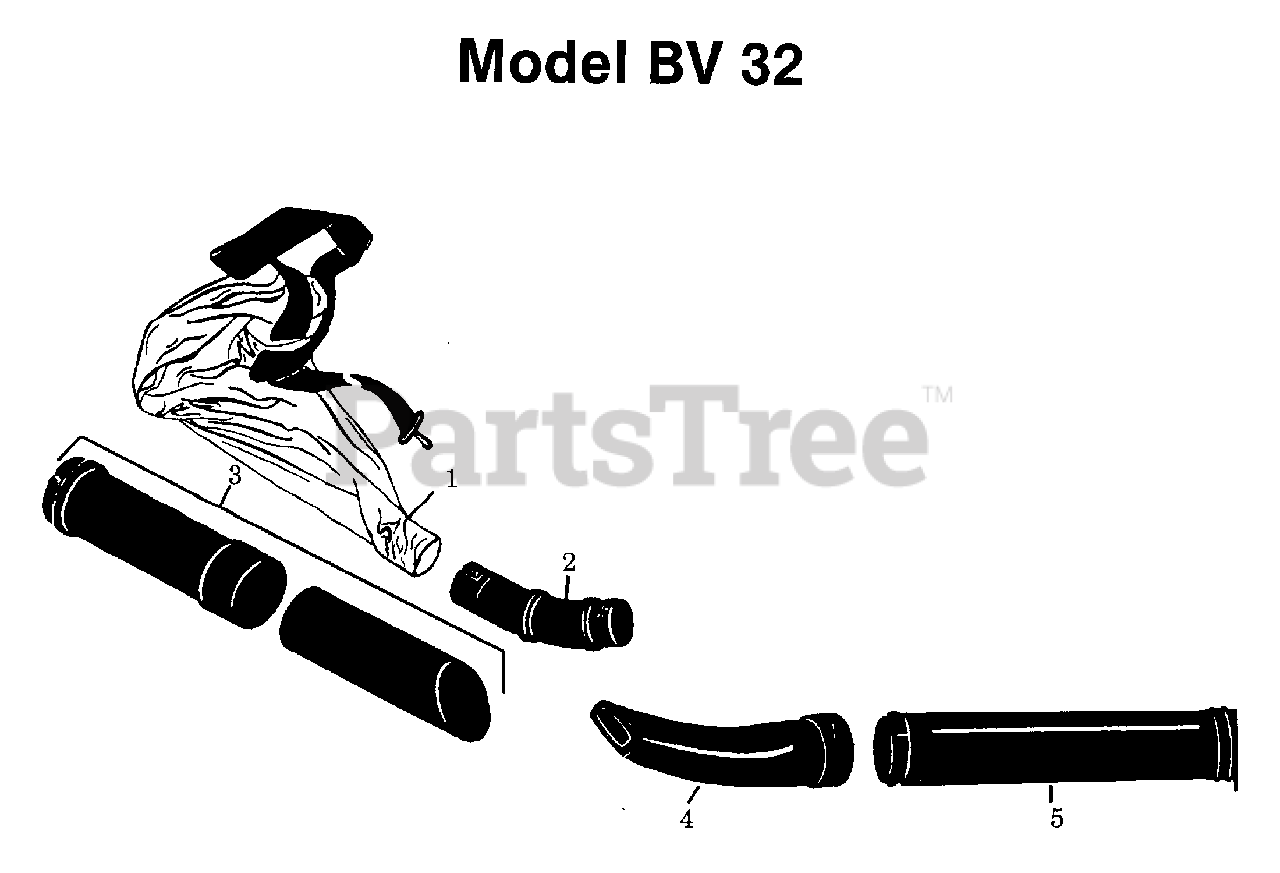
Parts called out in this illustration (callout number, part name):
1	COLLECTION BAG W/ STRAP
2	ELBOW TUBE
3	VAC TUBE SET
4	NOZZLE-BLOWER (FLARE)
5	TUBE-BLOWER (UPPER)
